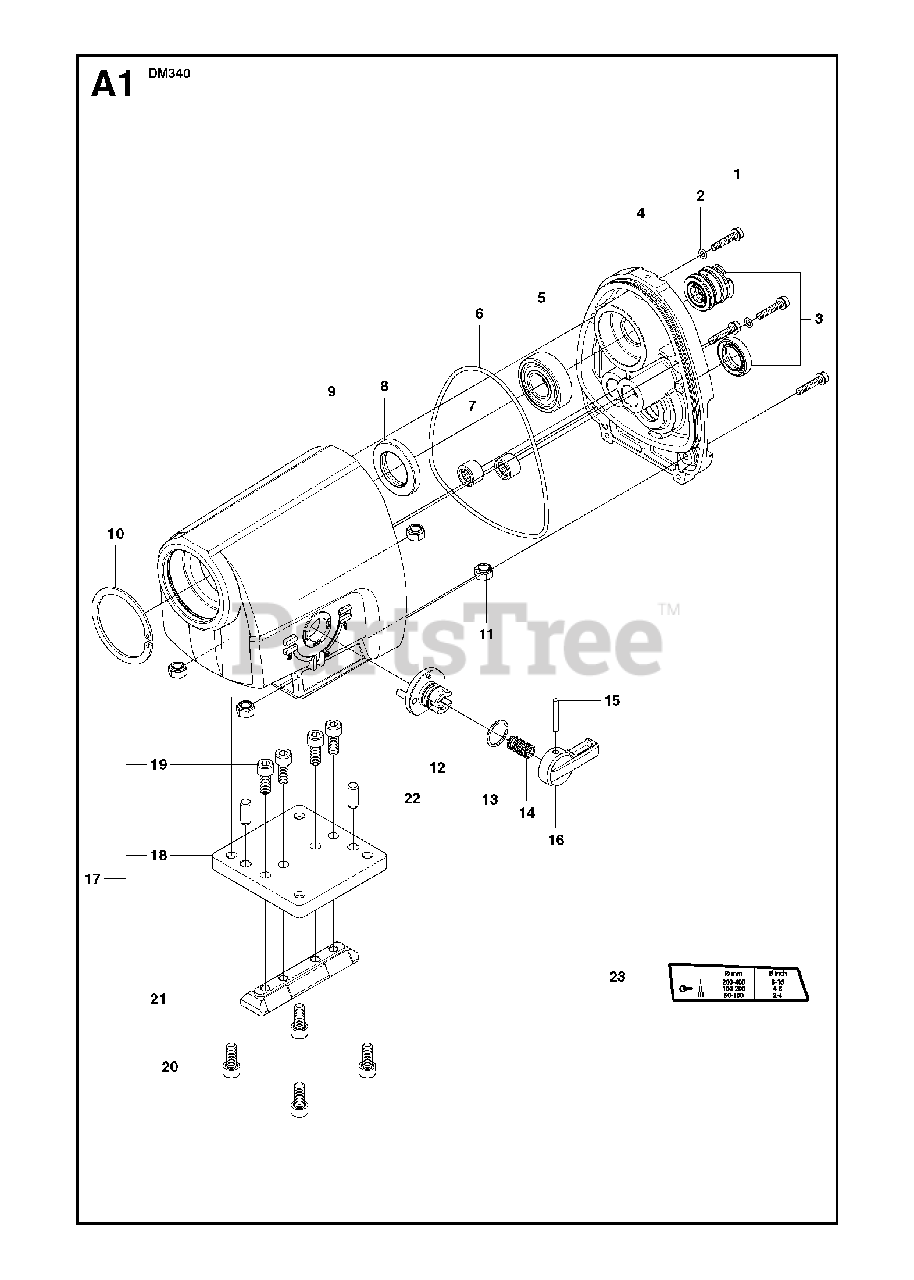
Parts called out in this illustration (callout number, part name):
1	SCREW IHSCFM
5	BALL BEARING
7	NEEDLE BEARING
11	HEXAGON LOCKING NUT
15	PARALLEL PIN
17	MOTOR BRACKETIncl. 18, 19 and 21
22	PARALLEL PIN
